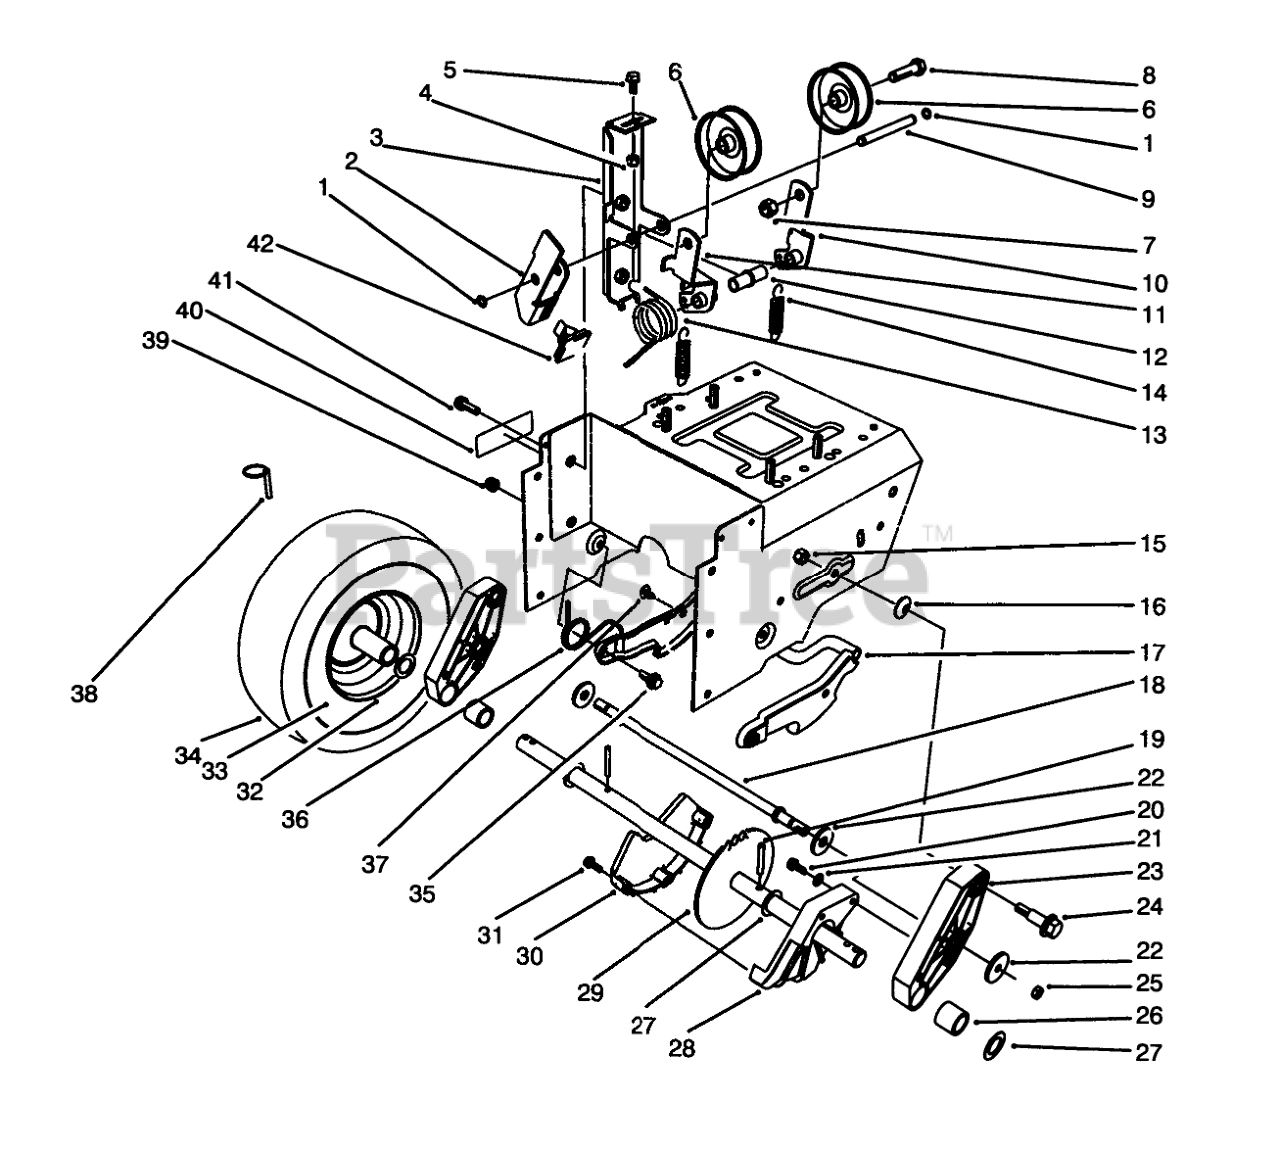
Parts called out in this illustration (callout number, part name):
1	RING-RETAINING
2	ARM-BRAKE
3	IDLER ARM BRACKET ASM
4	NUT-LOCK, NI
5	SCREW-HHF
6	PULLEY-IDLER
7	NUT-LOCK, NI
8	SCREW-HH
9	PIN-IDLER
10	ARM-IDLER, TRACTION
11	ARM-IDLER, IMPELLER
12	BUSHING-IDLER
13	SPRING-TORSION
14	SPRING-EXTENSION
15	NUT-LOCK, NI
16	WASHER-SPRING
17	Latch-Arm
18	ROD-LATCH
19	PIN-ROLL, SLOTTED
20	SCREW-HWH
21	WASHER-FLAT
22	WASHER-SUPPORT
23	Pivot Arm Assembly (Incl. Ref. #26)
24	BOLT-SHOULDER
25	NUT-LOCK, NI
26	BUSHING-AXLE
27	WASHER-THRUST
28	GUARD-CHAIN, LH
29	AXLE ASM
30	GUARD-CHAIN, RH
31	Screw
32	WHEEL
33	TUBE-INNER
35	SCREW-SHOULDER
36	SPRING-LATCH, TORSION
37	FASTENER-PANEL
38	PIN-LYNCH
39	NUT-LOCK, NI
40	DECAL-WARNING
41	SCREW-HHF
42	PAD-BRAKE
